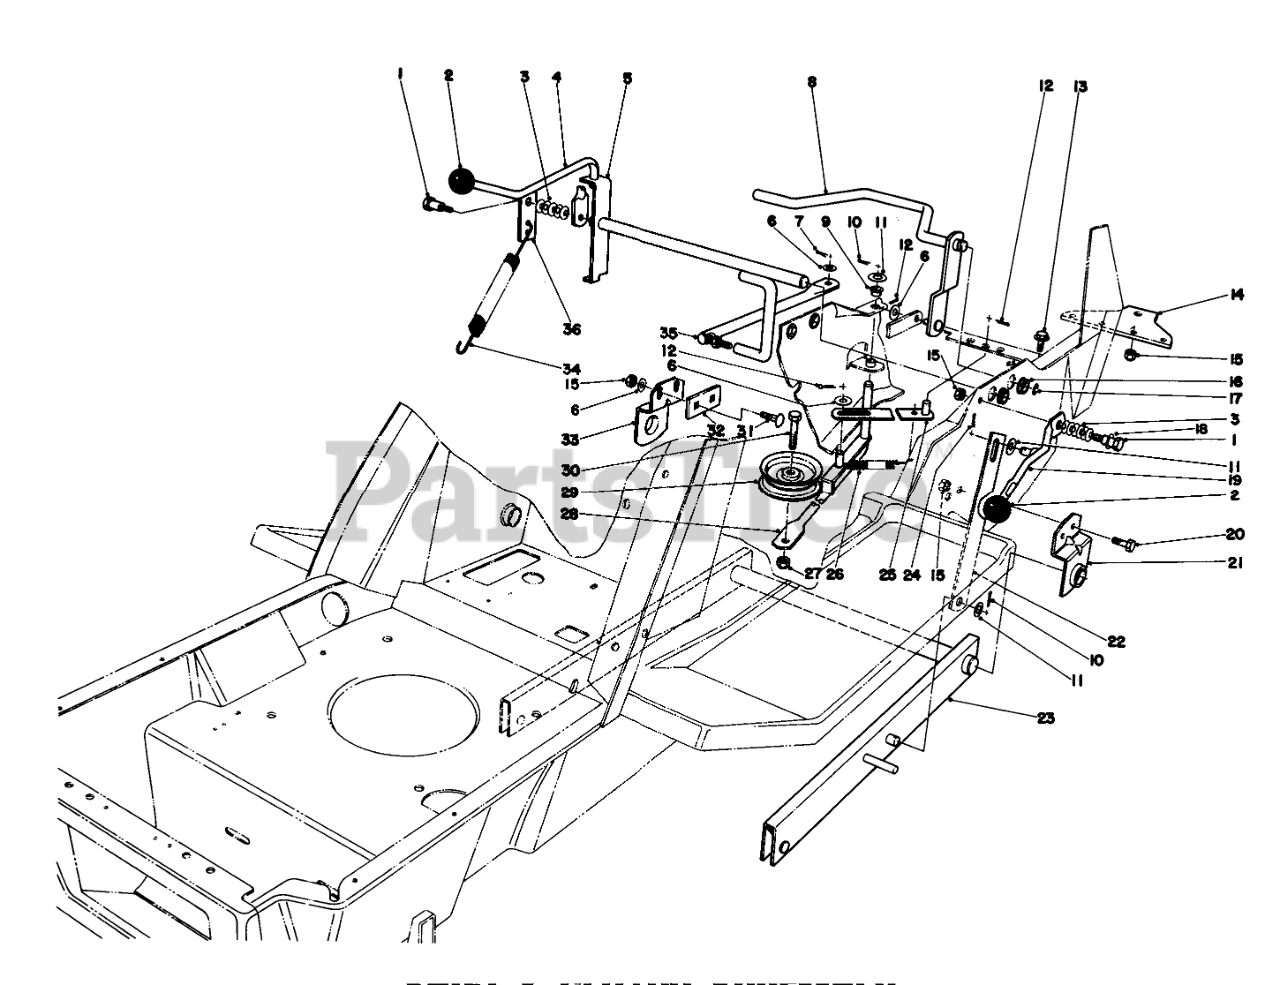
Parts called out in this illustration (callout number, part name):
1	BOLT-SHOULDER
2	Knob
3	WASHER-BELLEVILLE
4	SHIFT LEVER BO
5	Shim Lever
6	WASHER-PLAIN
7	PIN-COTTER
8	CLUTCH ACTUATOR WA B
9	BUSHING-NYLINER
10	PIN-COTTER
11	WASHER-FLAT
12	PIN-COTTER
13	SCREW-HHF
14	HITCH PLATE R
15	NUT-LOCK, CONE
16	Nyliner
17	E-RING
18	WASHER-FLAT
19	HOC HANDLE WA B
20	SCREW-HH
21	LH PIVOT BAR RET B
22	H.O.C. STRAP B
23	Bar-Pivot
24	PIN-COTTER
25	SPRING RET WA B
26	DECK TENSION SPRNG O
27	NUT-LOCK, CONE
28	IDLER ARM WA BO
29	IDLER PULLEY
30	SCREW-HH
31	BOLT-CARR
32	SPACER
33	RH PIVOT BAR RET B
34	TRACTION SPRING
35	SHIFT ARM BO
36	BRKT-COBALANCE SPRING
